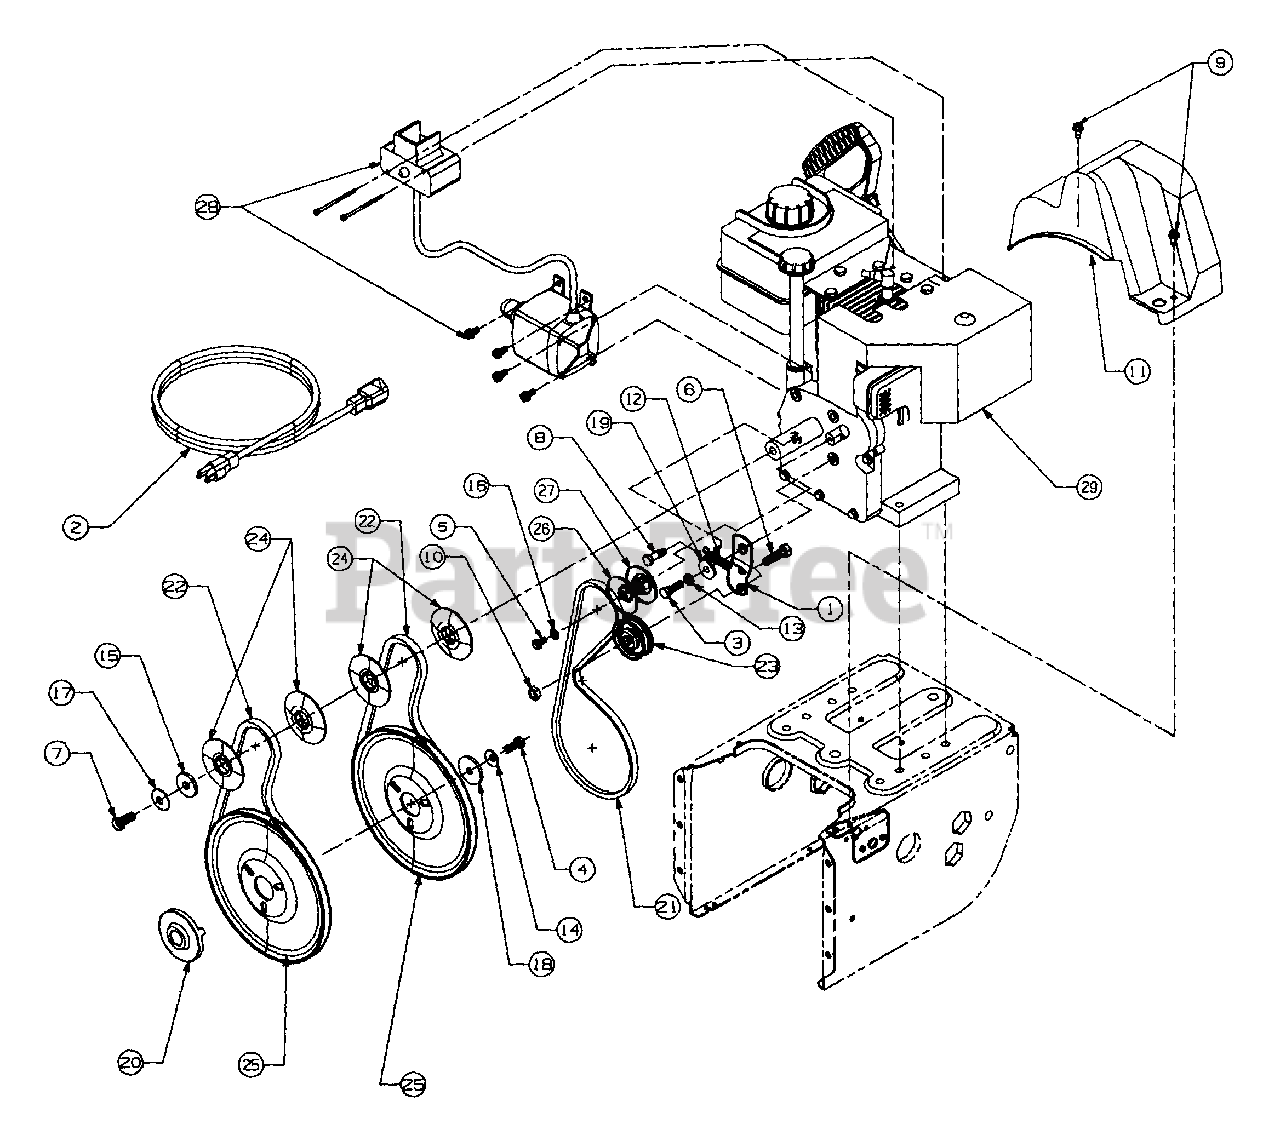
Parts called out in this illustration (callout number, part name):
3	Screw
4	Screw
5	Screw
6	Screw
7	Screw
8	Screw
9	Screw
10	Nut, Hex
11	Belt Cover
12	Spring
13	Washer - Flat
14	Washer - Bell
15	Washer - Flat
16	Washer - Lock
17	Washer - Bell
18	Washer - Flat
19	Shoulder Spacer
20	Pulley, Adapter
21	V-Belt
22	V-Belt Matched
23	Idler, Flat
24	Pulley, Half
25	Pulley - Auger
26	Pulley Half
27	Pulley Half
28	Starter
29	Engine
